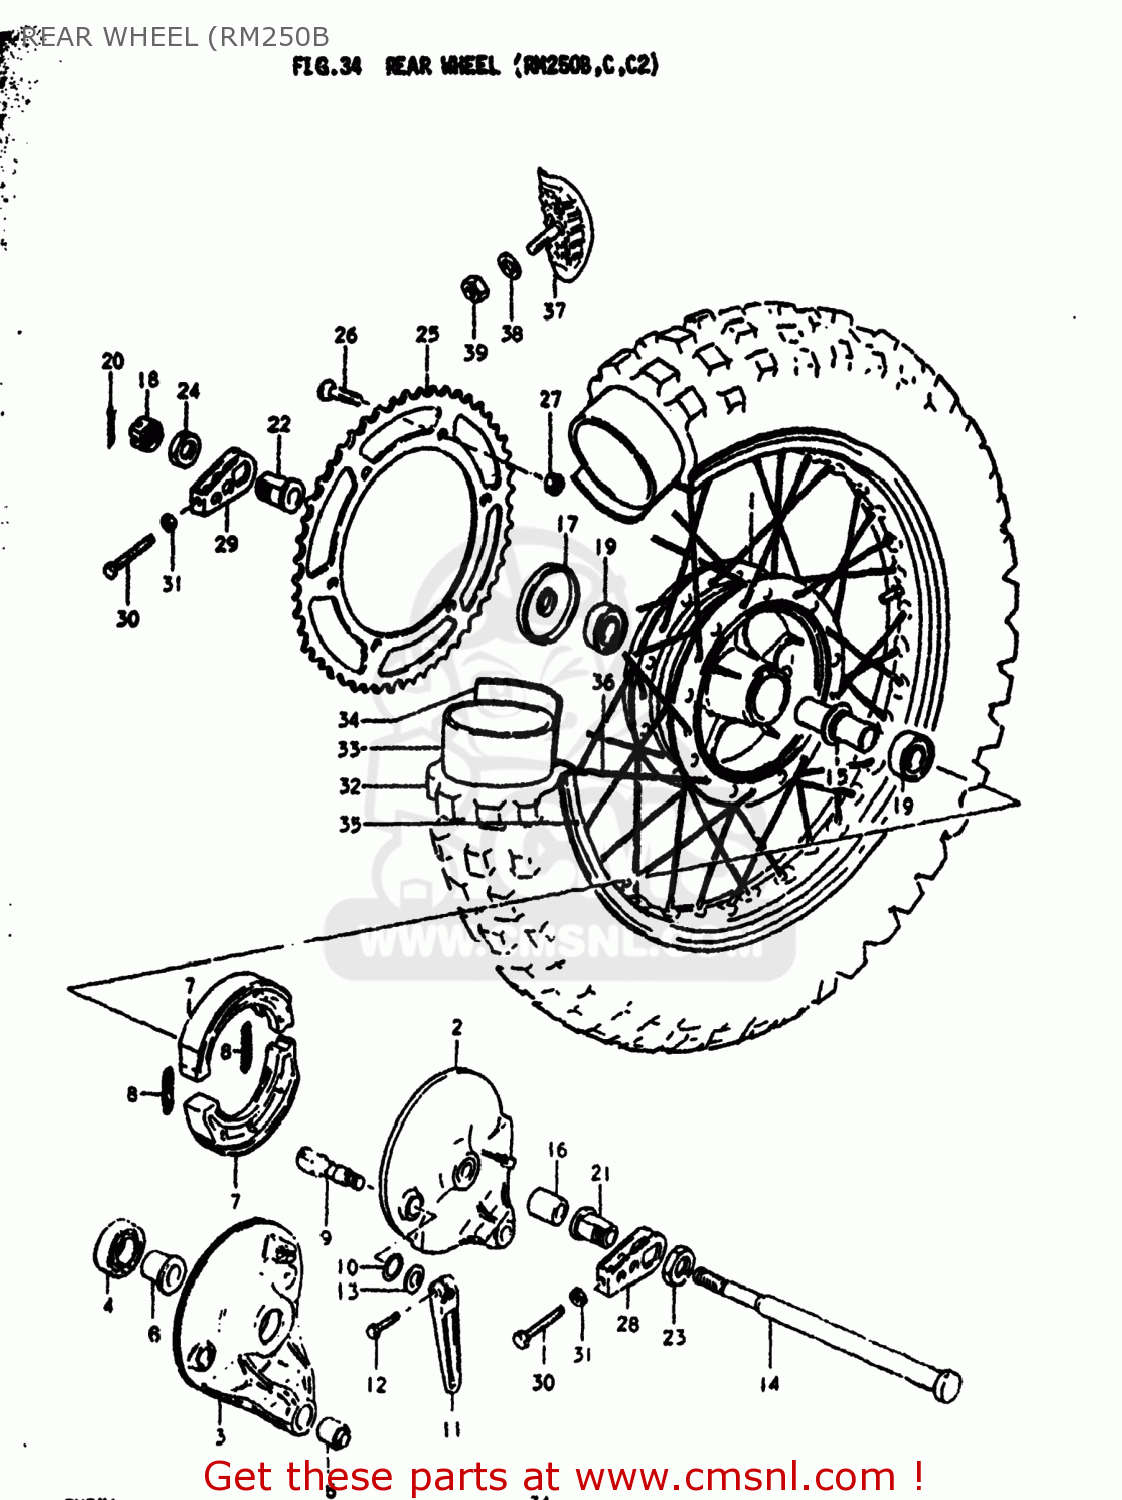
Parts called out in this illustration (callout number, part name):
1	HUB REAR
2	PANEL,REAR HUB
3	PANEL,REAR HUB
4	BEARING,RR SPROCKET DRUM
5	BUSH
6	SPACER,REAR HUB PANEL
7	SHOE,BRAKE
8	SPRING
9	CAM,FRONT BRAKE
10	O RING(D:3.2,ID:12.9)
11	LEVER,FRONT BRAKE CAM
12	BOLT
13	WASHER (15X24X1.6)
14	AXLE,REAR
15	SPACER,REAR HUB BEARING
16	SPACER
17	SPACER,REAR AXLE
18	NUT
19	BEARING
20	PIN 30X40
21	SPACER,CHAIN ADJUSTER
22	SPACER,CHAIN ADJUSTER
23	NUT
24	NUT
25	SPROCKET,REAR
26	SCREW
27	NUT
28	ADJUSTER,CHAIN
29	ADJUSTER,CHAIN
30	BOLT
31	NUT
32	TIRE
33	TUBE ASSEMBLY,WHEEL,INNER
34	PROTECTOR,WHEEL,INNER
35	RIM,REAR WHEEL
36	SPOKE SET,REAR
37	STOPPER,BEAD
38	WASHER
39	NUT
